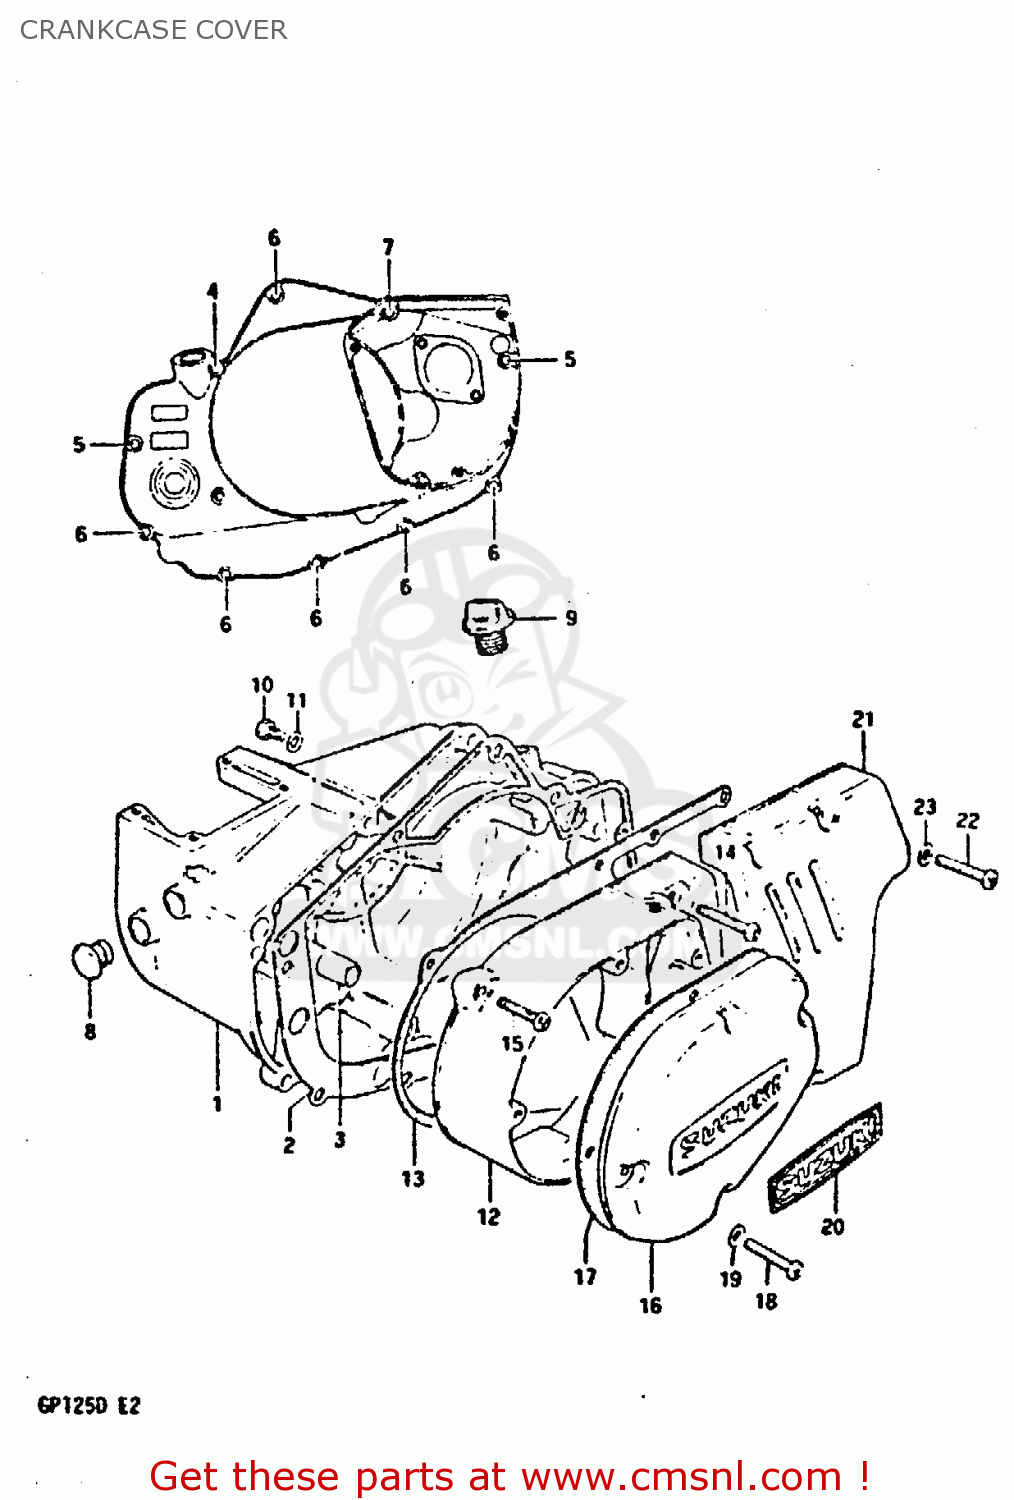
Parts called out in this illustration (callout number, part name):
1	COVER, CLUTCH
2	GASKET, CLUTCH COVER (MCA)
3	PIN
4	SCREW
5	SCREW
6	SCREW
7	SCREW
8	Plug
9	PLUG,OIL FILTER
10	SCREW(6X10)
11	GASKET(6.2X11X1) (NAS)
12	COVER, MAGNETO
13	GASKET (MCA)
14	SCREW (6X35)
15	SCREW
16	CAP, MAGNETO INSPECTION
17	GASKET,MAGNETO INSPECTION CAP (NAS)
18	SCREW
19	WASHER
20	EMBLEM,MAG INSPECTION CAP
21	COVER, ENGINE SPROCKET
22	SCREW (6X35)
23	WASHER
